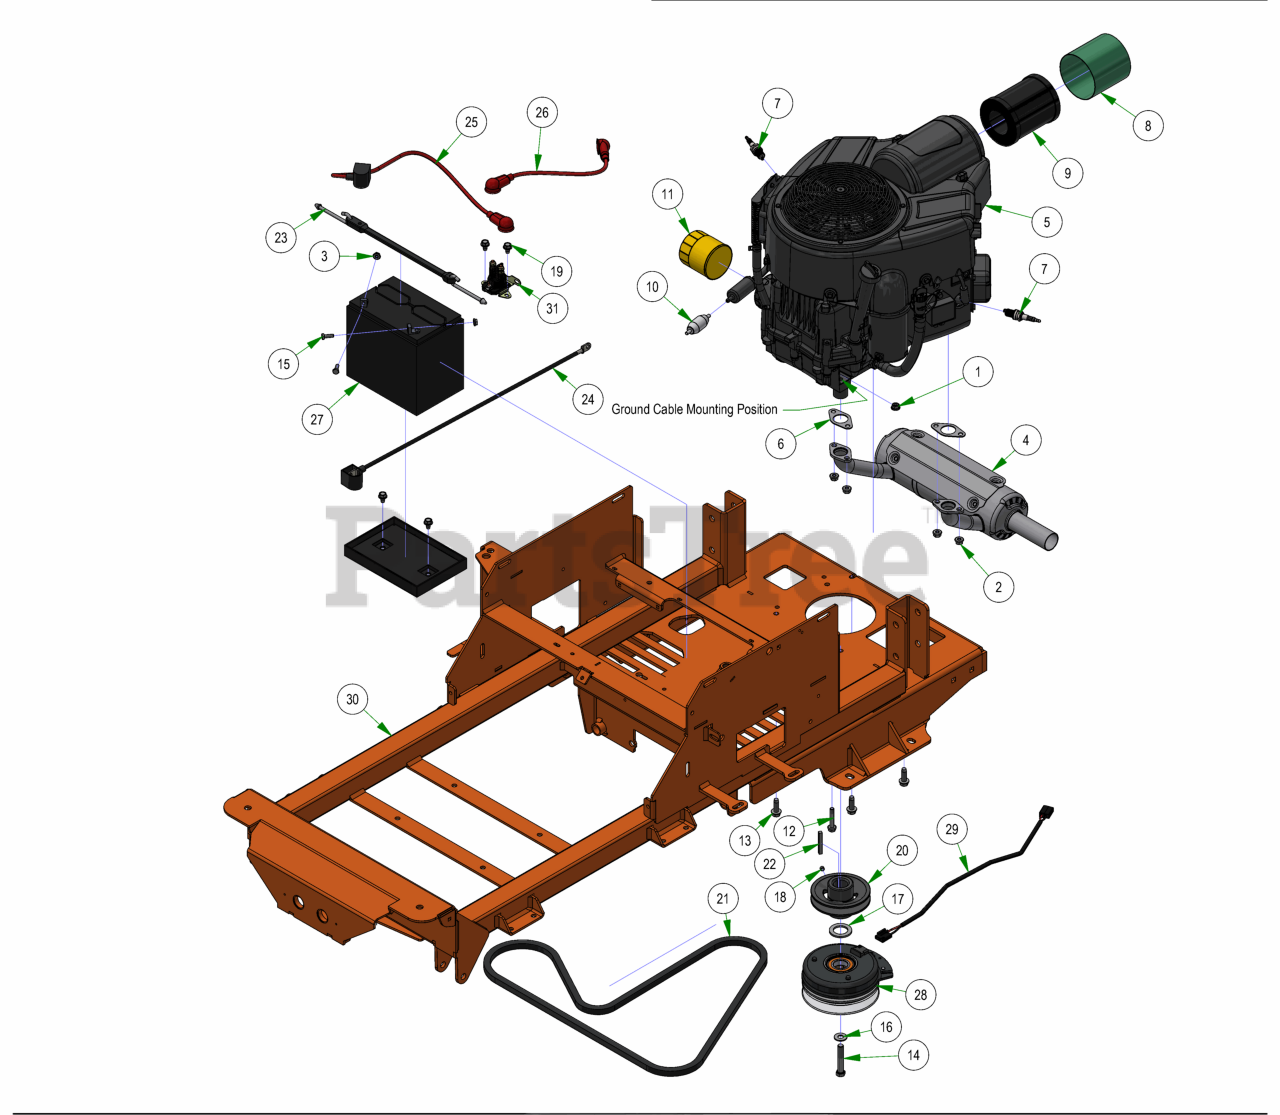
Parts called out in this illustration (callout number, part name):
1	5/16-18 Gr5 Distorted-Thread Flange Locknut
2	Muffler Nut for 015-0511-00 Briggs
3	1/4-20 HEX SERRATED FLANGE NUT HARD/ZINC
4	2017 Compact Outlaw Exhaust 810 Vanguard
5	Vanguard 27hp CXI with Out Oil Filter Maverick
6	Exhaust Gasket
7	Spark Plug
8	pre-Cleaner for Vanguard CXI Engine
9	Air Filter for Vanguard CXI Engine
10	Universal Inline Fuel Filter
11	Oil Filter
12	5/16-18x1-3/4 Gr5 Hex Flange Screw Zinc Clear
13	3/8-16 X 1-1/8 HEX WASHER UNSLOT SERRATED (TRI-LOB) TRS ZINC YELLOW
14	7/16-20 X 2.5" HEX Bolt GR.8 W/Patch
15	1/4-20 X 3/4 HEX CAP SCREW (GR.5) ZINC
16	3/8 FLAT WASHER USS (1" OD) ZINC
17	1.140 ID X 1.750 OD X .132 THICK FLAT WASHER PLAIN
18	5/16-24 X 1/4 SOCKET SET SCREW (CUP PT) PLAIN
19	5/16-18 X 1/2 HWH unslot (F) tcs zinc
20	4 3/4 Motor Pulley
21	75.8" Pump Belt
22	1/4 X 2 SQ MACHINERY KEY 1018 STL PLAIN
23	2023 Battery Hold Down Assembly
24	24 inch Black Cable – MZ/ZT
25	24" Red Battery Cable
26	12" Red Battery Cable
27	SP-35 Battery
28	120 Ft Lb. Clutch - 1 1/8" Shaft
29	Clutch Pigtail
30	2025 Maverick Frame
